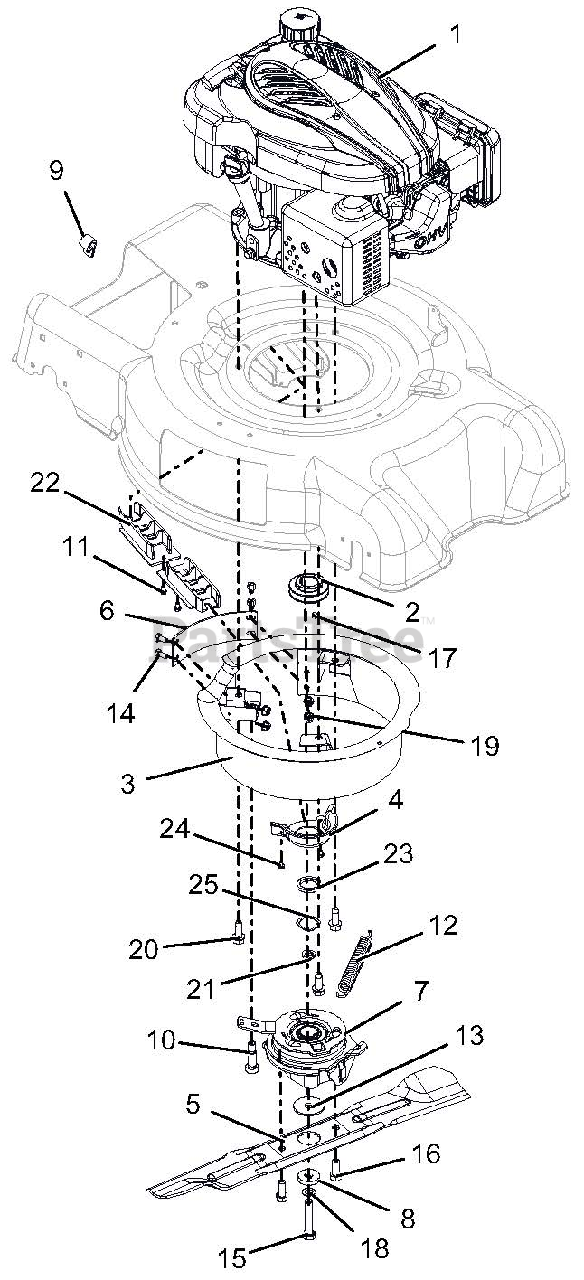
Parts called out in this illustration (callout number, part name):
1	ENGINE, LONCIN 159CC VERT. BBC
2	PULLEY, GROUND DRIVE, LM
3	WLDMT, ENCLOSURE - BBC
4	GUIDE, BELT CRANK
5	BLADE, MOWER 21" HIGH LIFT-BBC
6	BAFFLE, BBC
7	CLUTCH, RAZOR/XD3, 25MM
8	WSHR-FL-STL .44X1.25X.25 YWZC
9	CLAMP, LM CABLE
10	BLT,SHLDR 12MM X 25 W/ M10 THD
11	SCR-TAP 10-24X.375 PRE-COAT 80
12	SPRING, EXTENSION BBC
13	WSHR-FL-STL .469X1.75X.10 YWZC
14	@BLT-HEX .25-20X.50 GR5 YWZC
15	@BLT-HEX .4375-20X2.25 GR8 YWZ
16	BLT-HEX M10 X 1.5X25 YWZC
17	KEY-SQ .188X.188X.375
18	WSHR-FL-STL .45X.75X.033
19	@NUT-LK-TOP-FLG .25-20 YWZC
20	@SCR-TAP .38-16X1.00 HWH TR YZ
21	WSHR-FL-STL .459X.750X.105 YZC
22	GUIDE, BELT INNER
23	SPCR, 1.00 X 1.375 X .179
24	SCR-TAP 10-24X.25 CRSLPH TR YZ
25	WASHER - WAVE 1.09X1.37X.016
